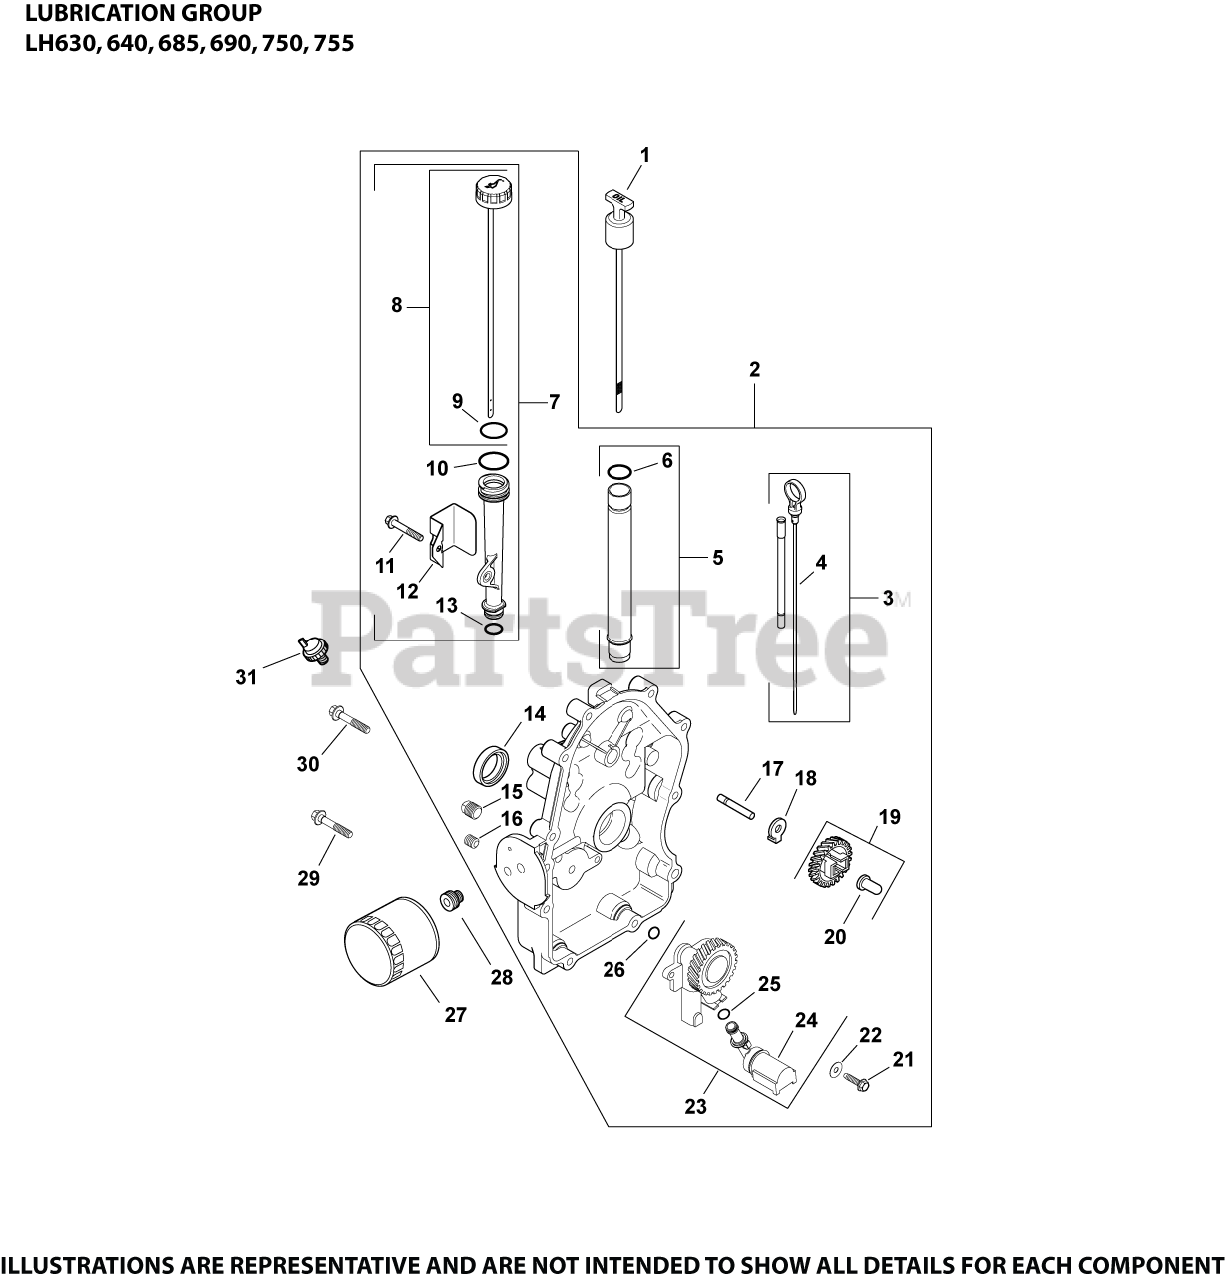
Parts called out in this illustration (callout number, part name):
2	CLOSURE PLATE ASSEMBLY USE 24 009 211-S
3	KIT, DIPSTICK/DIPSTICK TUBES
14	SEAL, OIL
16	PLUG, CTSK PIPE 1/8"
17	SHAFT, GOVERNOR GEAR
18	TAB, LOCKING
19	KIT, GOVERNOR GEAR W/PIN
20	PIN, GOVERNOR REGULATING
21	SCREW, THREAD FORMING
22	WASHER, FLAT 1/4" (O.D. 5/8")
23	KIT, OIL PUMP ASSEMBLY
24	PICK-UP, OIL
25	O-RING, OIL PICK-UP
27	OIL FILTER
28	NIPPLE, OIL FILTER
29	SCREW, FLG M8X1.25X45
30	SCREW - DISCONTINUED
31	SENSOR, OIL PSI
